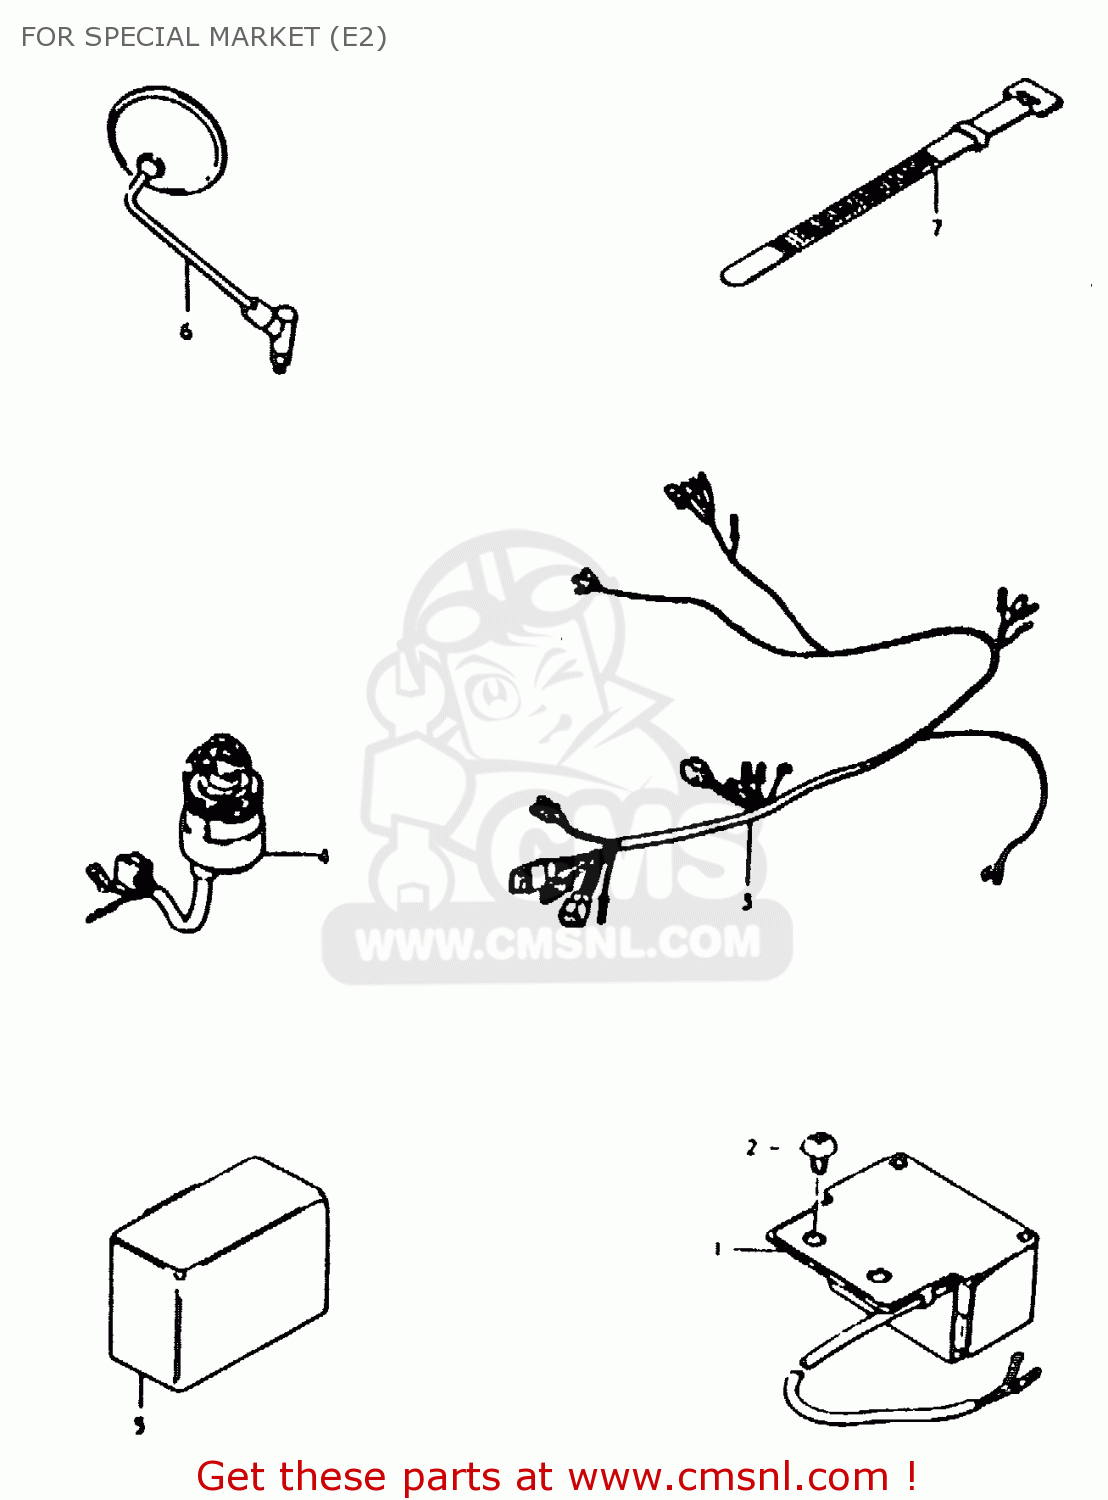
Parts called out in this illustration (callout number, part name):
1	RESISTOR ASSY
2	SCREW
3	WIRING HARNESS NO.2
4	SWITCH ASSY, IGNITION
5	RELAY,TURN SIGNAL
6	MIRROR ASSY,RH
7	CLAMP(L:120)
